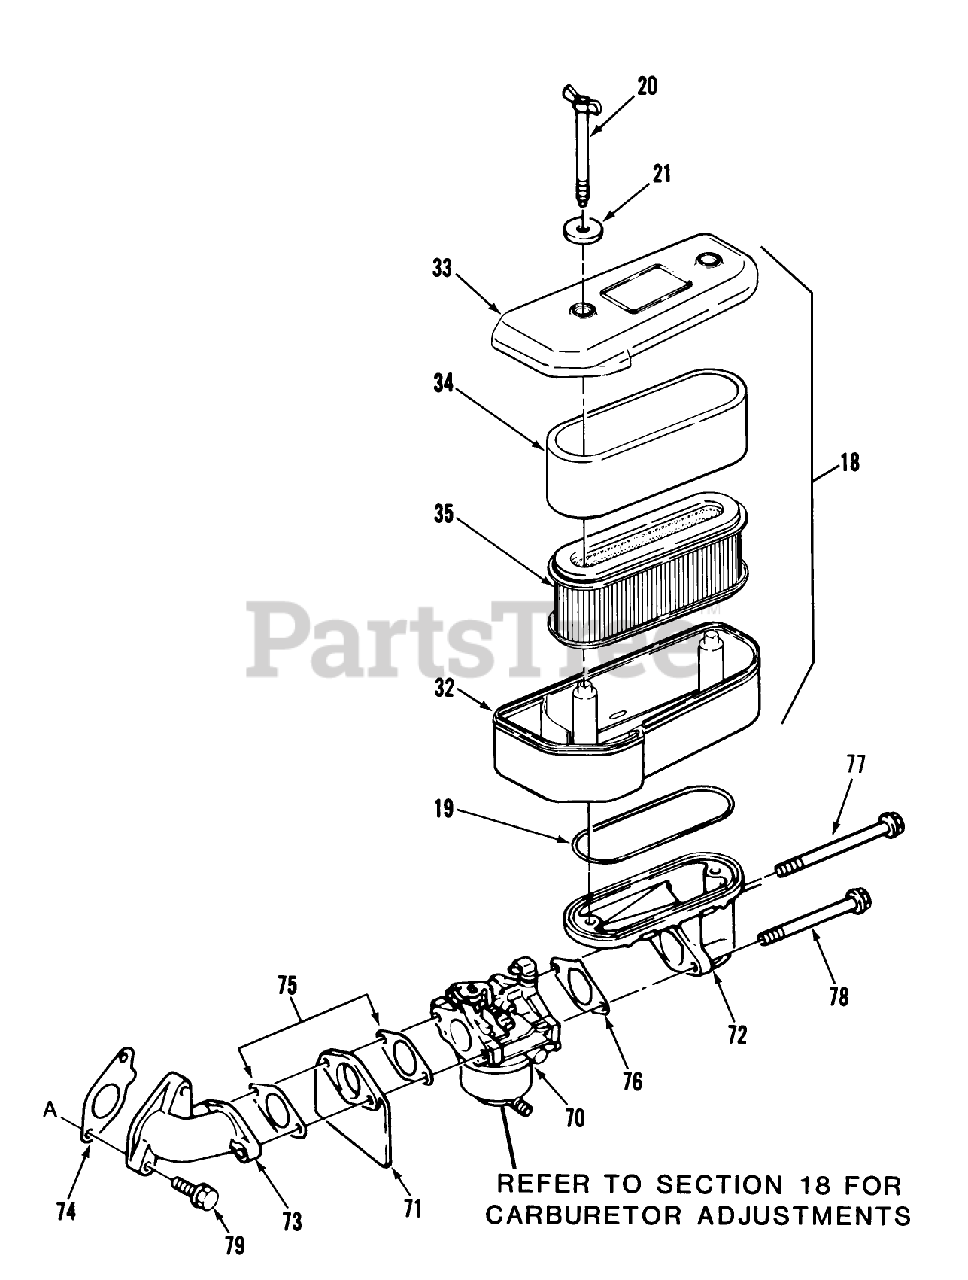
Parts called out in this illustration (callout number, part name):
18	AIR FILTER ASSY
34	ELEMENT-AIR CLEANER
73	MANIFOLD INTAKE
74	GASKET
